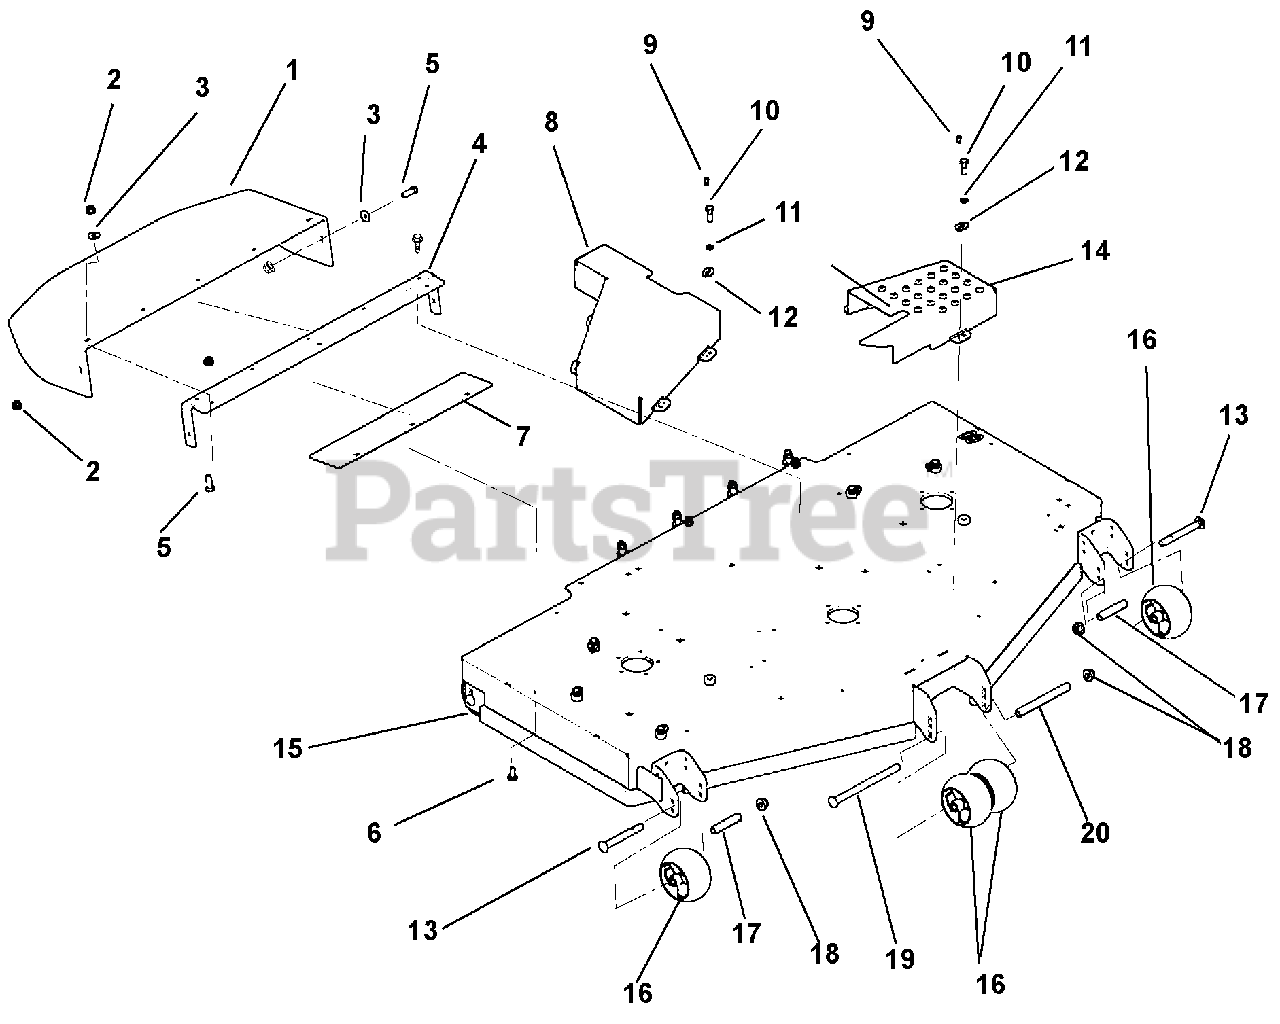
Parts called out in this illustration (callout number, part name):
1	Chute, Rubber Discharge
2	Nut, Locking, Nylon, Flange .38-16
3	Washer, Flat Steel .438 x 1.00 x .083
4	Support, Rubber Discharge Chute
5	Bolt, Hex .38-16 x 1.25
6	Bolt, Round Head Square Neck .38-16 x 1.00
7	Plate, Discharge Chute Support
8	Guard, Belt, Right – 60" Deck
9	Rivet, Pop, 0.187
10	Bolt, Hex 0.38-16 x 1.25
11	Washer, Locking, Ext. 0.391 x 0.628 x 0.036
12	Keeper, Bolt
13	Bolt, Round Head Square Neck .50-13 x 5.00
14	Guard, Belt, Left Hand Spindle
15	Weldment, 60" Rear Discharge Deck
16	Anti-Scalp Wheel
17	Spacer, .510 x .625 x 3.35
18	Nut, Locking, Nylon Flange .50-13
19	Bolt, Round Head Square Neck .50-13 x 8.50
20	Spacer, .510 X .625 x 6.70
